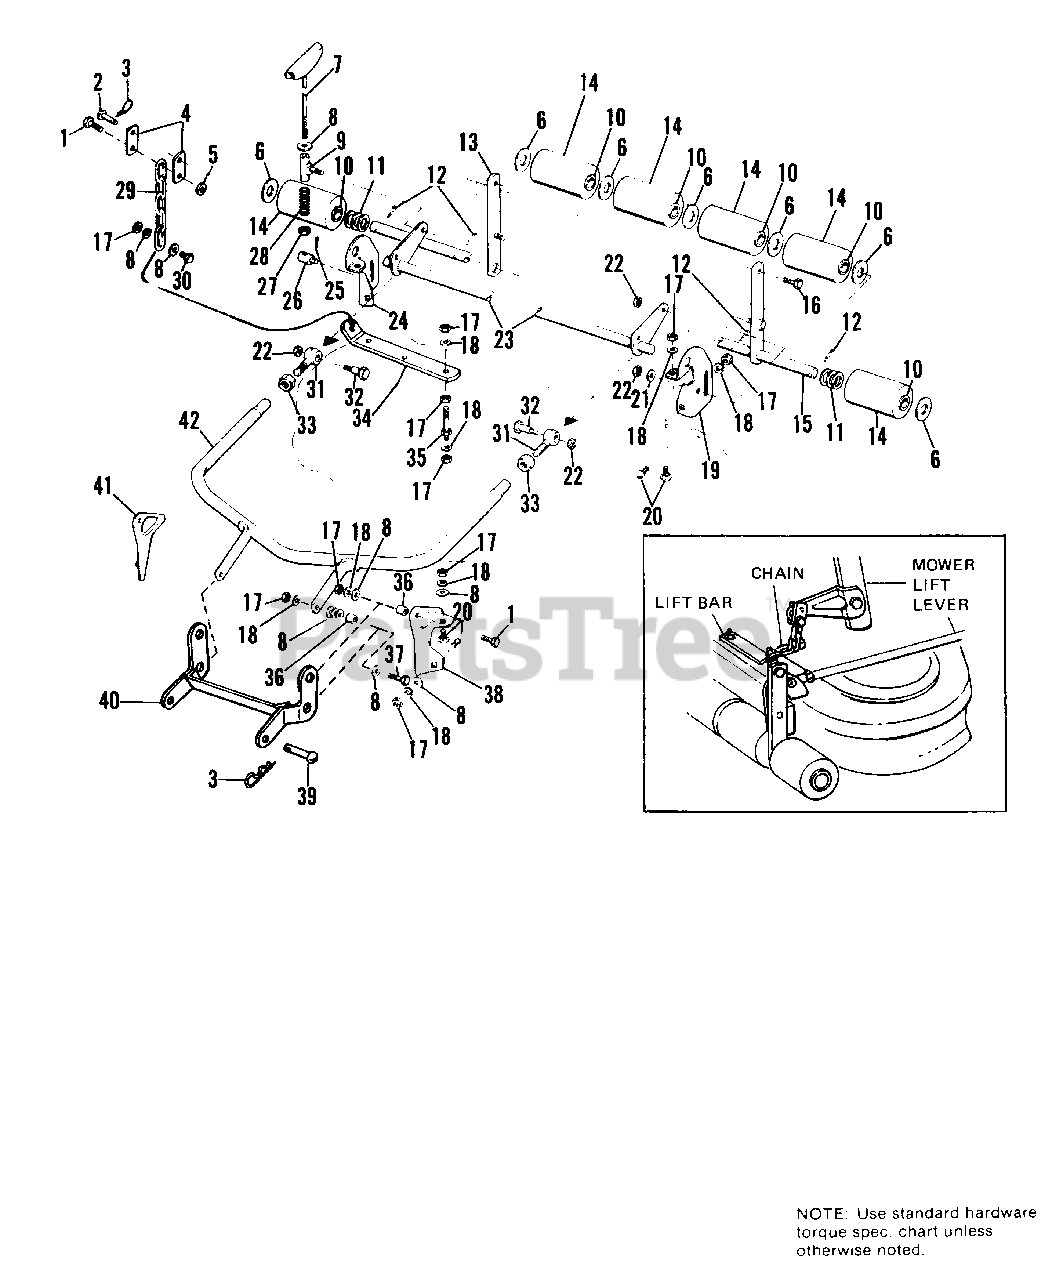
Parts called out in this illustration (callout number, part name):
1	CAPSCREW, Hex Hd., 3/8-16 x 1
3	CLIP, Hair Pin
4	LINK, Mower Lift
5	LOCKNUT, Hex, 3/8-16
7	SCREW ASSY., Adjusting
8	WASHER, Plain, 3/8
9	SOCKET ASSY., Crank
12	PIN, Cotter, 3/16 x 1
13	BAR ASSY., Roller
14	ROLLER ASSY., W/Bushings
15	ROLLER BAR & SHAFT ASSY.
16	CAPSCREW, Hex Hd., 3/8-16 x 7/8
17	NUT, Hex, Full, 3/8-16
18	LOCKWASHER, 3/8
19	BRACKET, Roller, L.H.
20	BOLT, Carriage, 3/8-16 x 3/4
21	WASHER, Plain, 5/16
22	LOCKNUT, Hex, 3/8-16
23	LEVER ASSY., Rear
24	BRACKET, Roller, R.H.
25	PIN, Cotter, 3/32 x 3/4
27	LOCKNUT, Hex, Jam, 3/8-16
29	CHAIN
30	CAPSCREW, Hex Hd., 3/8-16 x 3/4
32	BOLT, Shoulder
33	LOCKNUT, Hex, Jam, 1/2-20
34	BAR, Lift
37	CAPSCREW, Hex Hd., 3/8-16 x 1-1/4
38	BRACKET, Front, L.H.
40	ARM ASSY., Rocker
41	BRACKET, Front, R.H.
42	BAIL ASSY.
